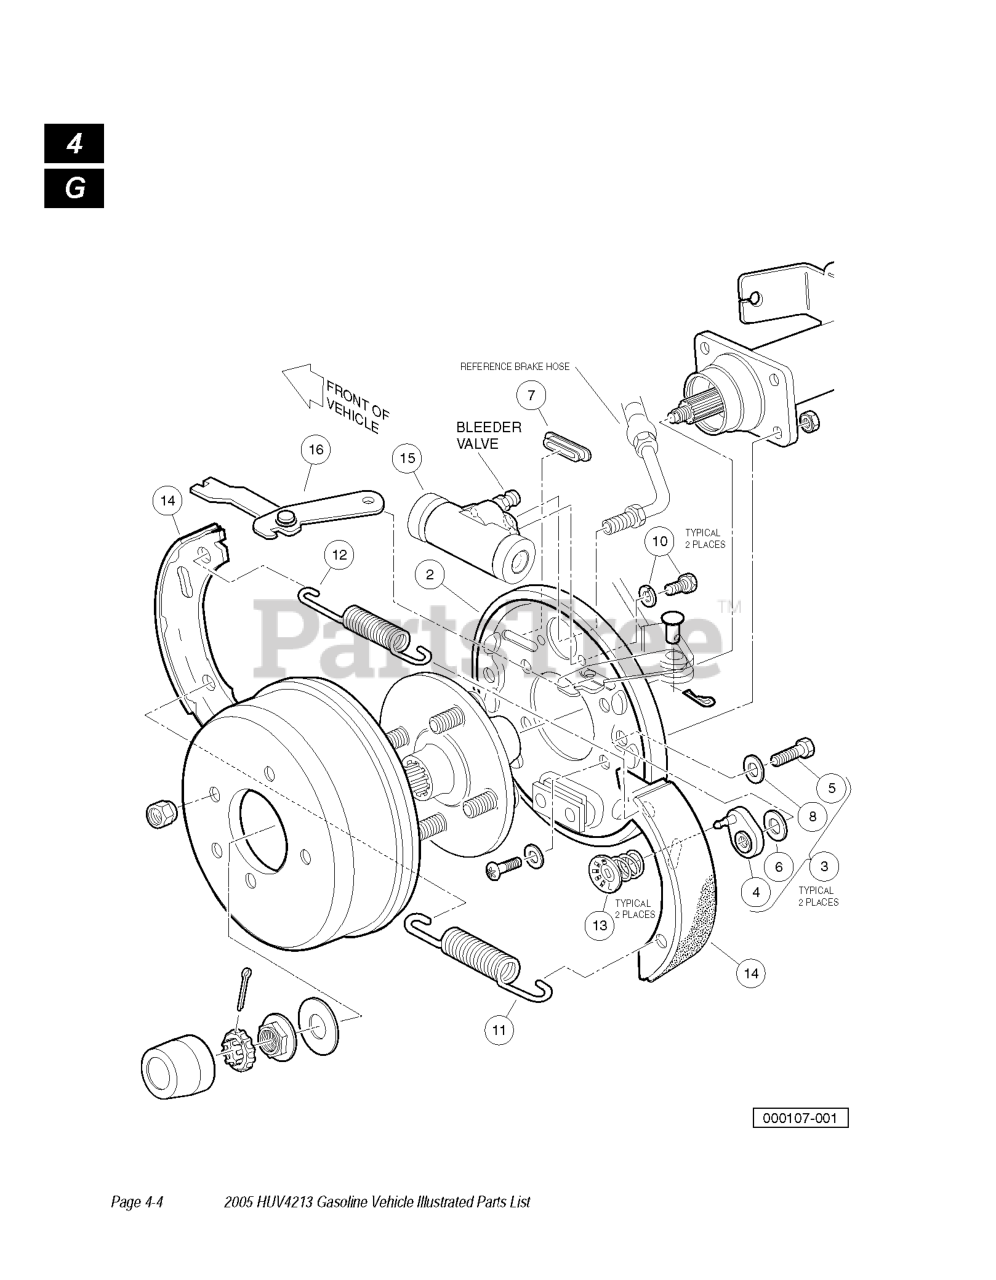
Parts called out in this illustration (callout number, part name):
1	BRAKE CLUSTER ASM L.H.
2	BACKING PLATE ASM
3	ADJUSTER KIT AXLE
5	BOLT, 1/4-28 UNF X .31 LG
7	DUST COVER
9	HARDWARE KIT - AXLE
10	BOLT, WHL CYL-M6 X 1 SELF LOCK
11	SPRING, SHOE TO SHOE - LOWER
12	SPRING, SHOE TO SHOE UPPER
13	SHOE HOLD DOWN
14	SHOE KIT - AXLE SET
15	WHEEL CYL ASM .875 DIA.
16	PARKING BRAKE ASM L.H.
17	BRAKE CLUSTER ASM R.H.
18	BACKING PLATE ASM
19	ADJUSTER KIT AXLE
21	BOLT, 1/4-28 UNF X .31 LG
23	DUST COVER
25	HARDWARE KIT - AXLE
26	BOLT, WHL CYL-M6 X 1 SELF LOCK
27	SPRING, SHOE TO SHOE - LOWER
28	SPRING, SHOE TO SHOE UPPER
29	SHOE HOLD DOWN
30	SHOE KIT - AXLE SET
31	WHEEL CYL ASM .875 DIA.
32	PARKING BRAKE ASM R.H.
